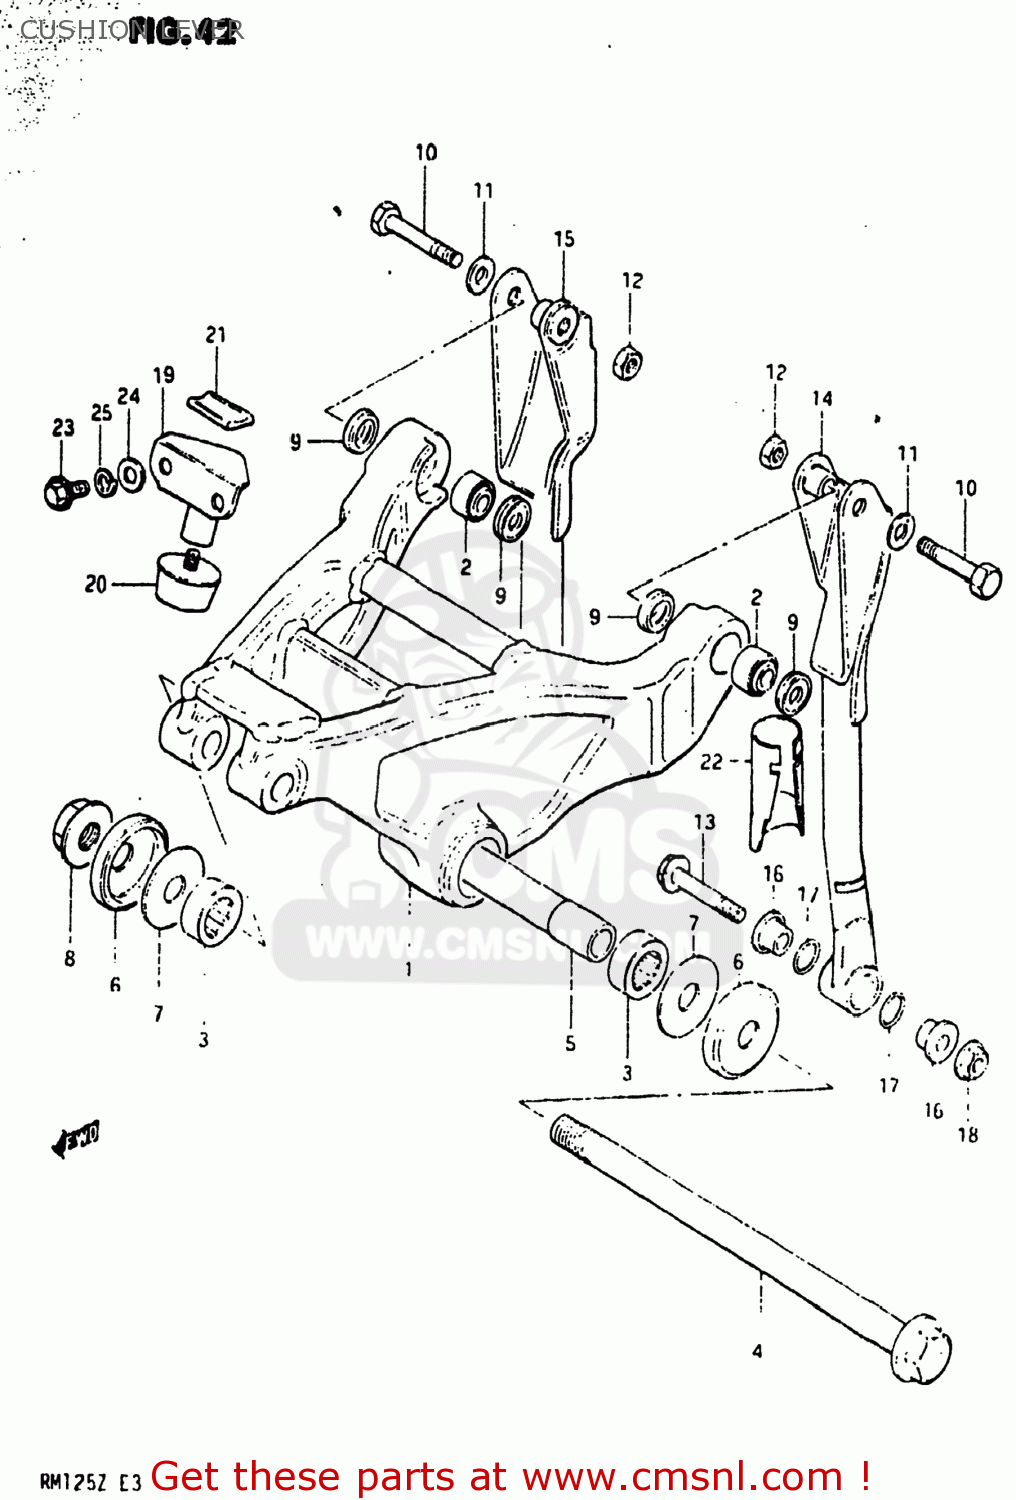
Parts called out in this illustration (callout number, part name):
1	LEVER SET,REAR CUSHION
2	BEARING(8X18X11)
3	BEARING(17X25X20)
4	SHAFT,REAR CUSHION LEVER
5	SPACER,REAR CUSHION LEVER
6	SEAL,REAR CUSHION LEVER
7	WASHER(12X35X2)
8	NUT 12MM
9	DUST SEAL,RR CUSHION LOD UPR.
10	BOLT 8X38
11	WASHER
12	NUT 8MM
13	BOLT 8X45
14	ROD,REAR CUSHION LEVER
15	BOLT,REAR CUSHION LEVER
16	SPACER,RR CUSHION ROD LWR
17	O RING(D:1.9,ID:13)
18	NUT
19	STOPPER,TENSION
20	RUBBER,TENSION STOPPER
21	SUPPORTER, RUBBER
22	PROTECTOR,REAR CUSHION R
23	BOLT
24	WASHER
25	LOCK WASHER
